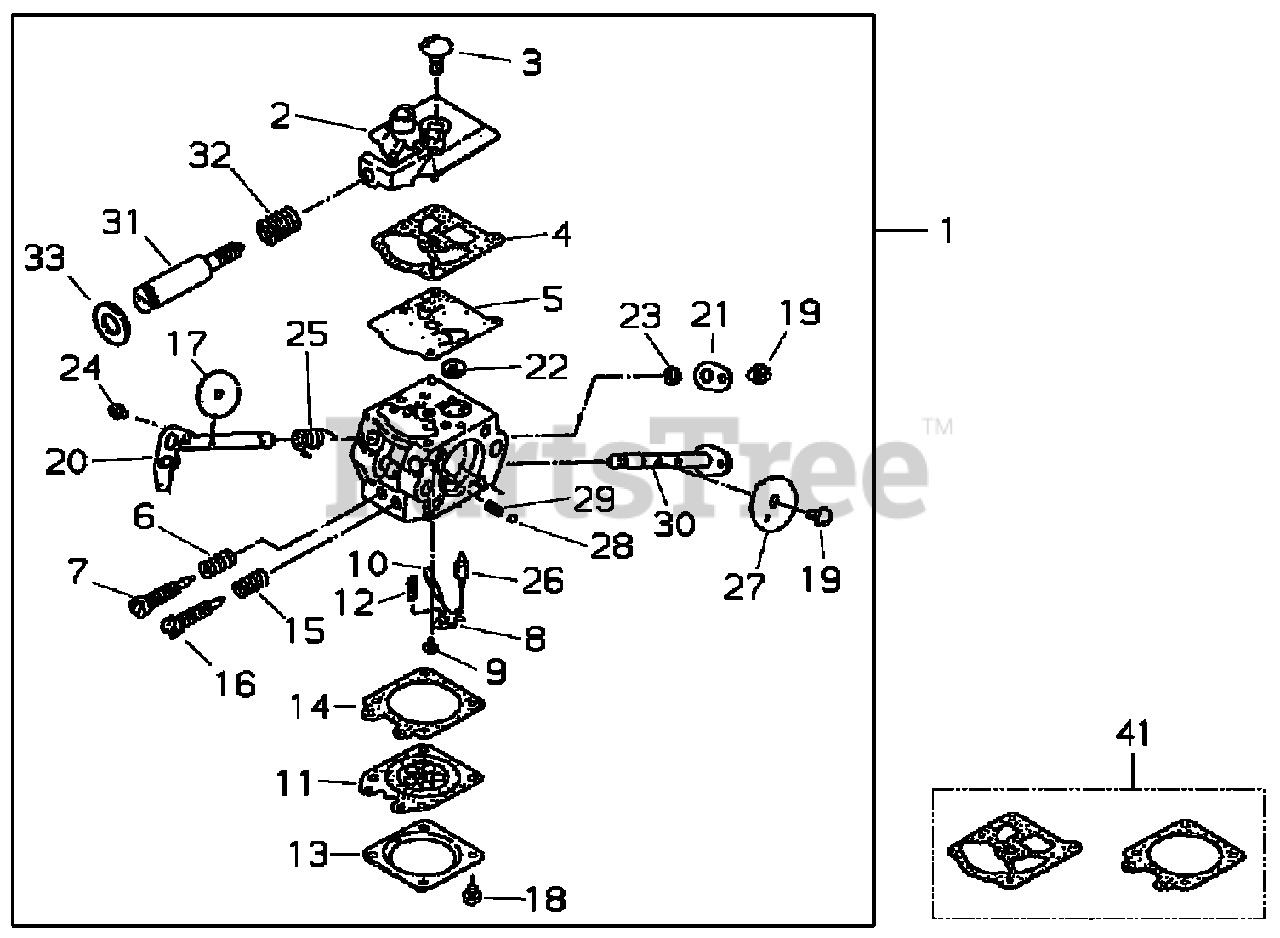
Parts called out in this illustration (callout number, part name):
1	CARBURETOR
2	COVER ASSY, PUMP
3	SCREW, PUMP COVER
4	GASKET, PUMP
5	DIAPHRAGM, PUMP
6	SPRING
7	NEEDLE - LOW SPEED
8	LEVER, METERING
9	SCREW, METERING LEVER PIN
10	PIN, METERING LEVER
11	DIAPHRAGM, METERING
12	SPRING, METERING LEVER
13	COVER, METERING
14	GASKET, METERING
15	SPRING
16	NEEDLE - HIGH SPEED
17	VALVE, THROTTLE
18	SCREW
19	SCREW
20	SHAFT, THROTTLE
21	LEVER, THROTTLE
22	STRAINER
23	RING, RETAINING
24	SCREW
25	SPRING, THROTTLE RETURN
26	VALVE, INLET NEEDLE
27	VALVE, CHOKE
28	BALL, CHOKE
29	SPRING
30	SHAFT, CHOKE
31	SCREW, IDLE ADJUST
32	SPRING, IDLE ADJUST
33	SEAL
41	GASKET KIT
